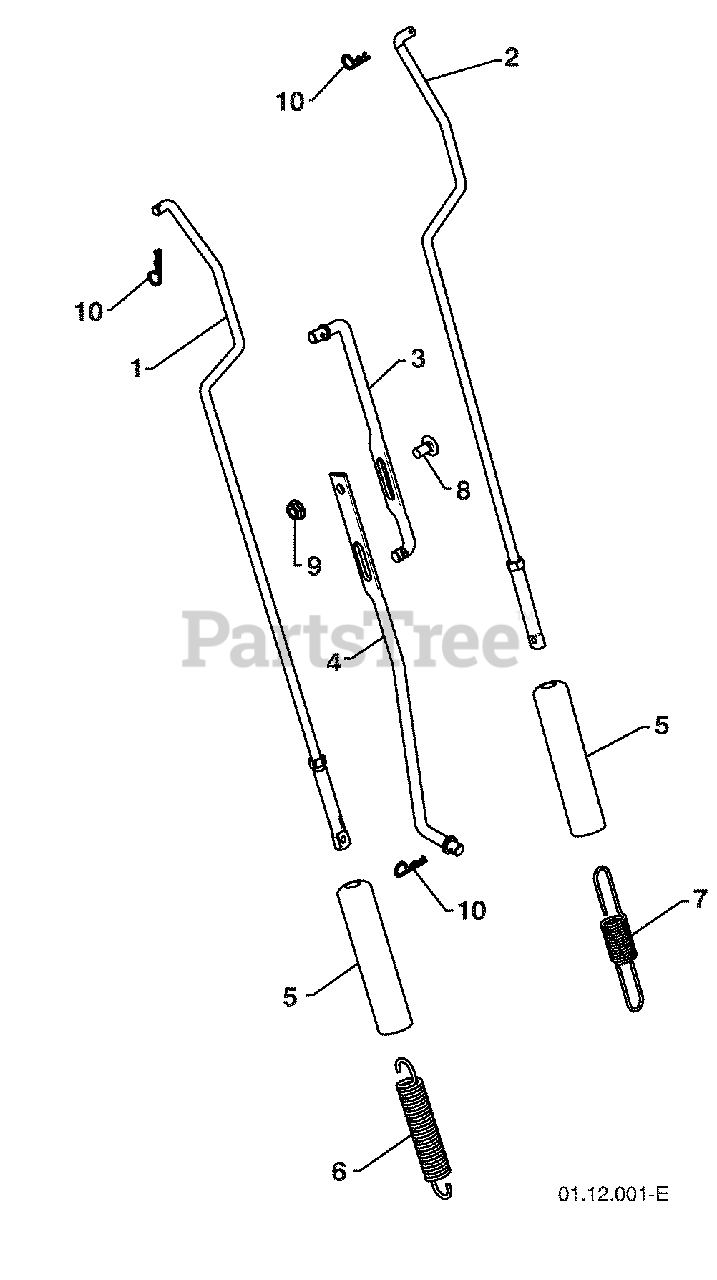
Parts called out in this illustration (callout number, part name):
1	IMPELLER ROD ASSEMBLY
2	TRACTION ROD ASSEMBLY
3	SHIFTER ROD TOP
4	SHIFTER ROD BOTTOM
5	SPRING SLEEVE
6	IMPELLER SPRING
7	TRACTION SPRING
8	CARRIAGE BOLT 5/16-18 X .75
9	NUT 5/16-18
